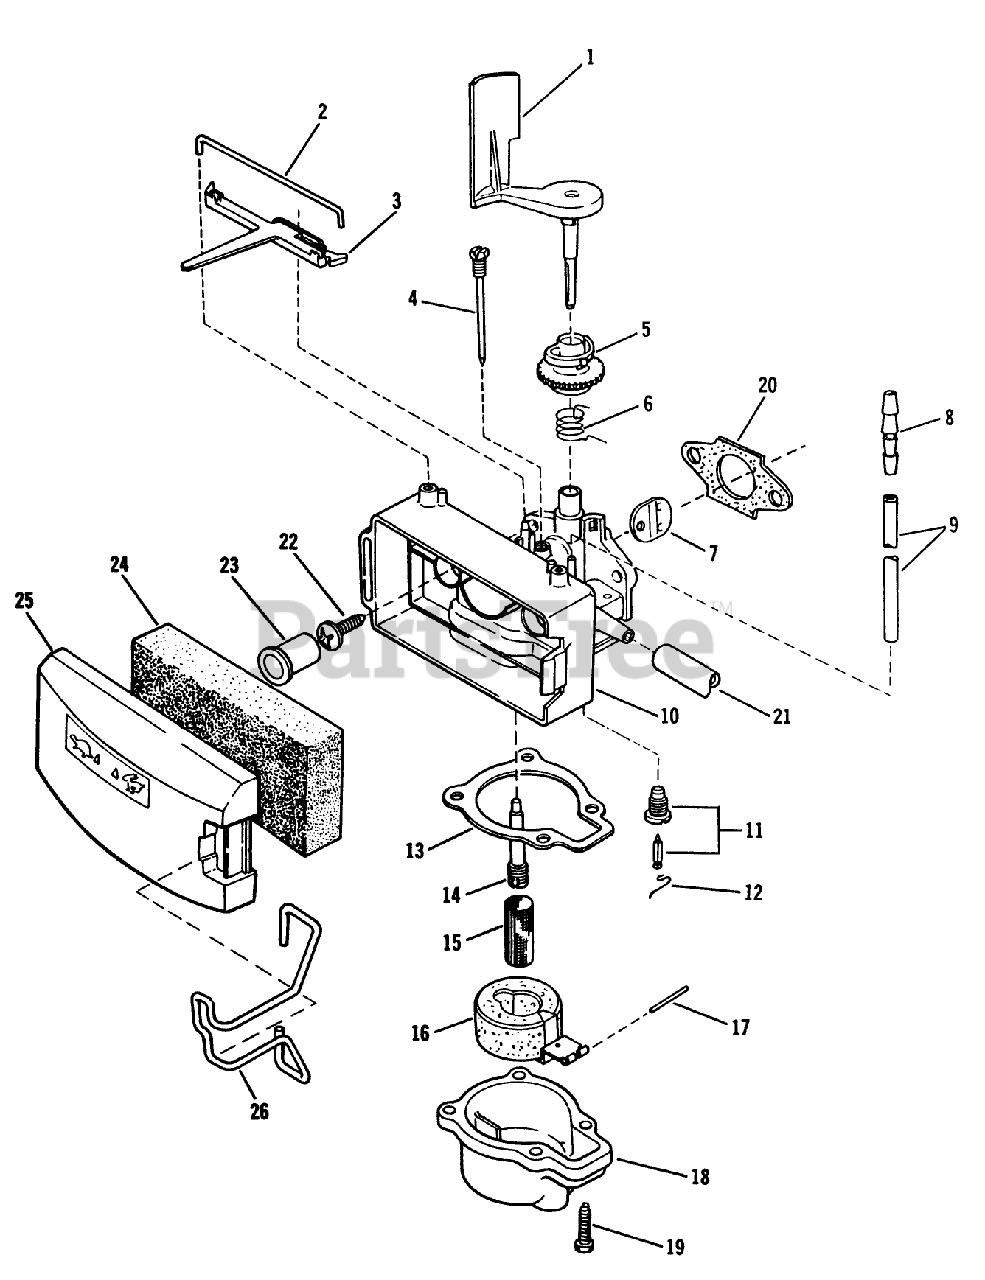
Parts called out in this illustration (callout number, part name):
2	RETAINER
3	LEVER S
4	NEEDLE ADJ. AY S
5	COLLAR-ADJUST, AIRVANE
6	SPRING,THROTTLE S
7	DISC S
8	REDUCER-CONNECTOR
9	TUBING S
10	CARB BODY S
15	FILTER-FUEL VS
19	SCREW-HH
20	GASKET CARB S
21	GAS LINE
22	SCREW
26	RETAINER-COVER, FILTER
